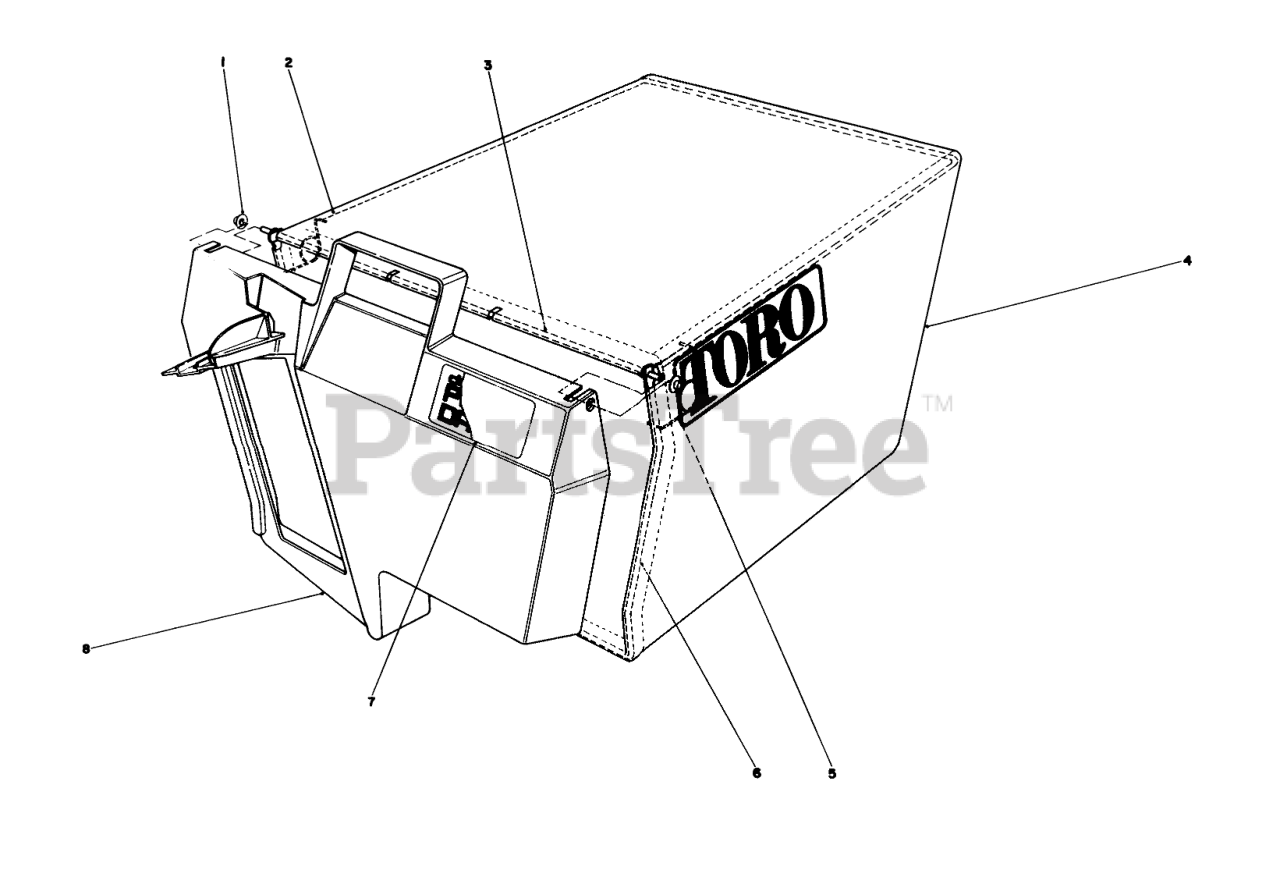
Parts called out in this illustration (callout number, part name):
1	NUT-PUSH
2	FRAME-BAG, UPPER
3	HINGE-DOOR, BAG
4	Bag
5	SPRING
6	FRAME-BAG
7	BAG DOOR DECAL
8	Door Grass Bag
